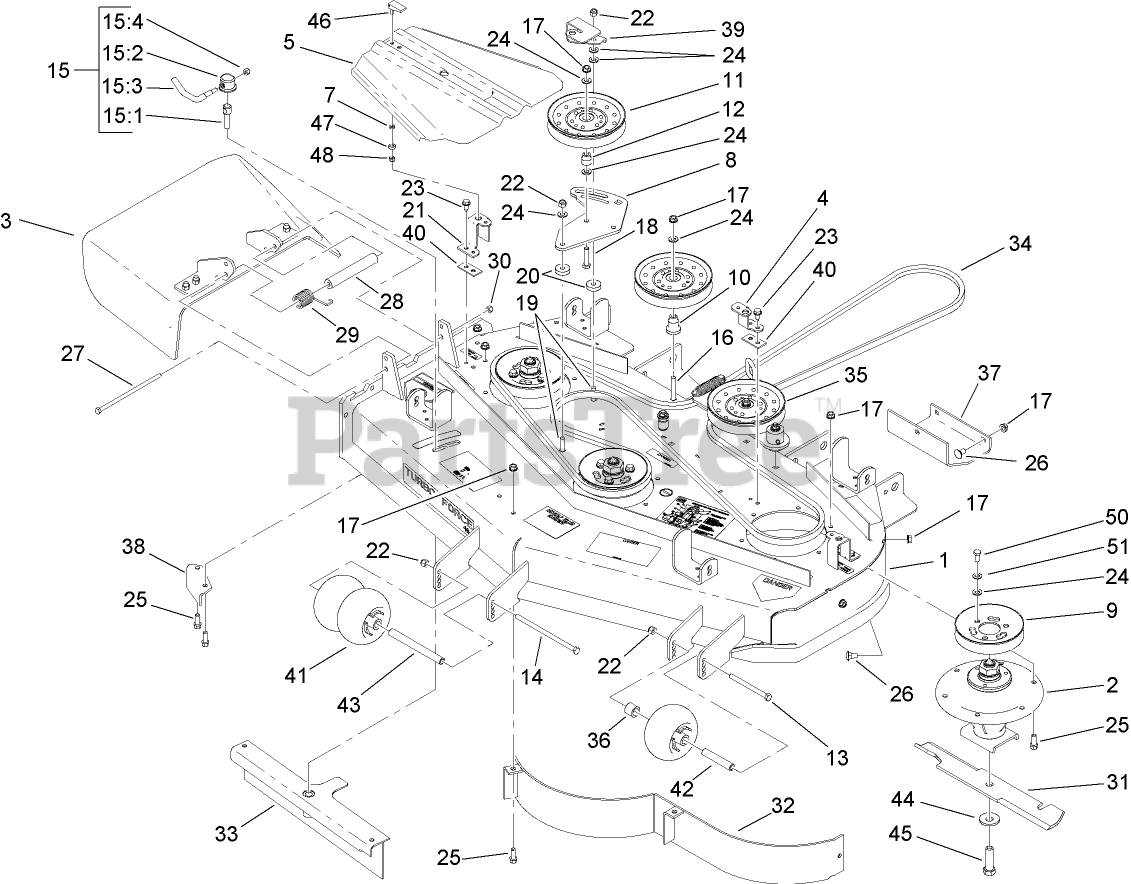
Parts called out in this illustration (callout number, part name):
1	DECK DECAL ASM
2	SPINDLE ASM
3	RUBBER DEFLECTOR ASM
4	BRACKET-COVER, TALL
5	COVER-BELT
7	WASHER
8	PLATE-IDLER
9	PULLEY
10	MOUNT-PULLEY
11	Idler-Flat
12	BUSHING-IDLER
13	SCREW-HH
14	SCREW-HH
15	LEVER ASM
15:1	Screw-Lock
15:2	CAP-LOCK
15:3	Lever-Lock
15:4	NUT-LOCK, NI
16	SCREW-CARR
17	NUT-HHF, WHIZ
18	SCREW-HH
19	SCREW-CARR
20	Spacer
21	BRACKET-COVER
22	NUT-LOCK, NI
23	SCREW-HWHTF
24	WASHER-FLAT
25	SCREW-HWH
26	SCREW-CARR
27	SCREW-HH
28	SPACER
29	SPRING-TORSION
30	NUT-LOCK, NI
31	BLADE-16.5 INCH (HIGH FLOW)
32	BAFFLE ASM
33	BAFFLE
34	BELT-V
35	SPRING IDLER ASM
36	TUBE-SPACER
38	BAFFLE-DISCHARGE
39	BRACKET-COVER
40	SPACER-COVER, BELT
41	ROLLER-SCALP, ANTI
42	TUBE-SPANNER
43	SPACER-WHEEL
44	Washer-Blade Bolt, Heavy
45	SCREW-BLADE
46	HANDLE-LATCH, SWELL
47	BUSHING-LATCH, SWELL
48	NUT-LOCK, HH
50	SCREW-HH
51	WASHER-BELLEVILLE
99	BLADE-ROTARY, 16.5 INCH (LOW FLOW)
99	BLADE-ROTARY, 16.5 INCH (MED FLOW)
99	BLADE-ROTARY, 16.5 INCH (ATOMIC)
99	BLADE-RECYCLER, 16.5 INCH
